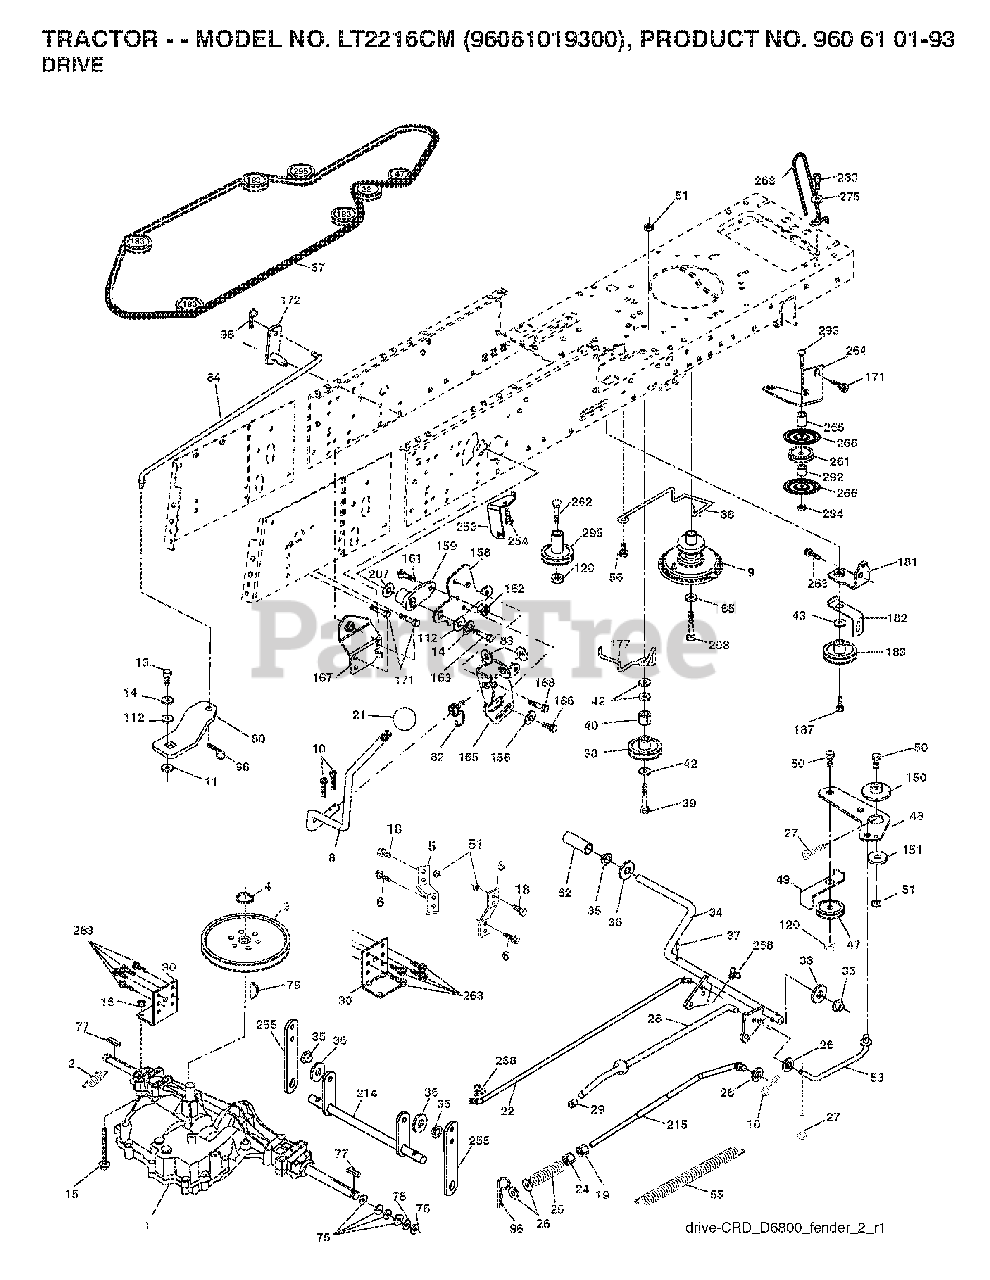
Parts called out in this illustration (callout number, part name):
2	SPRING,BRAKE RETURN
4	RETAINING RING LT
5	STRAP TORQUE
6	SCREW 5/16"
8	ROD SHIFT FENDER ADJUST LT
10	PIN COTTER
11	WASH-SHFT PLT LT
13	BOLT 1/4-28X3/4
14	LOCKWASHER
15	BOLT HEX 5/16-18 GR 5
16	NUT.71038.31-18.HEX.NYLOCK
19	NUT
21	KNOB.DUCKHEAD.1/2
24	NUT
25	SPRING ROD LT
27	COTTER PIN
28	ROD, PARKING BRAKE
29	PLUNGER CAP
30	BRKT, MOUNT TRNSAXLE
34	SHAFT, FOOT PEDAL
35	BEARING.NYLON
36	WASHER LT
37	DRIVE PIN
38	PULLEY.FLAT
42	WASHER
47	IDLER PULLEY
48	BELLCRANK, CLUTCH
49	RETAIN BELT
50	BOLT.3/8-16X1.50
51	LOCKNUT
53	LINK.CLUTCH.7.66.2005
55	SPRING, RETURN LT
56	SCREW.3/8-16
62	PEDAL COVER T
65	LOCKWASHER
66	KEEPER BELT ENGINE
76	E-RING LT
77	SQUARE KEY
80	ARM SHIFT
82	SHIFT SPRING
83	WASHER
96	RETAINER M
112	WASHER LT
120	NUT LOCK FLG 3/8-16 UNC
150	BUSHING.BELLCRANK.GRD.DR
151	WASHER 12/32X2X10GA
156	WASHER.SRRTD.5/16
158	BRACKET
159	HUB.SHIFT
161	BOLT
162	NUT.CROWNLOCK.1/4
165	RP BRACKET
167	BRACKET
168	BOLT.SHOULDER.5/16-18X
187	BOLT.5/16-18X1.25
207	WASHER NYL
254	SCREW 3/8-16X1
258	CLIP RETAINER
261	FLAT IDLER PULLEY
263	SCREW, 3/8-16X3/4
275	WASHER
294	NUT, HEX 3/8-16
295	PULLEY IDLER COMPOSITE
